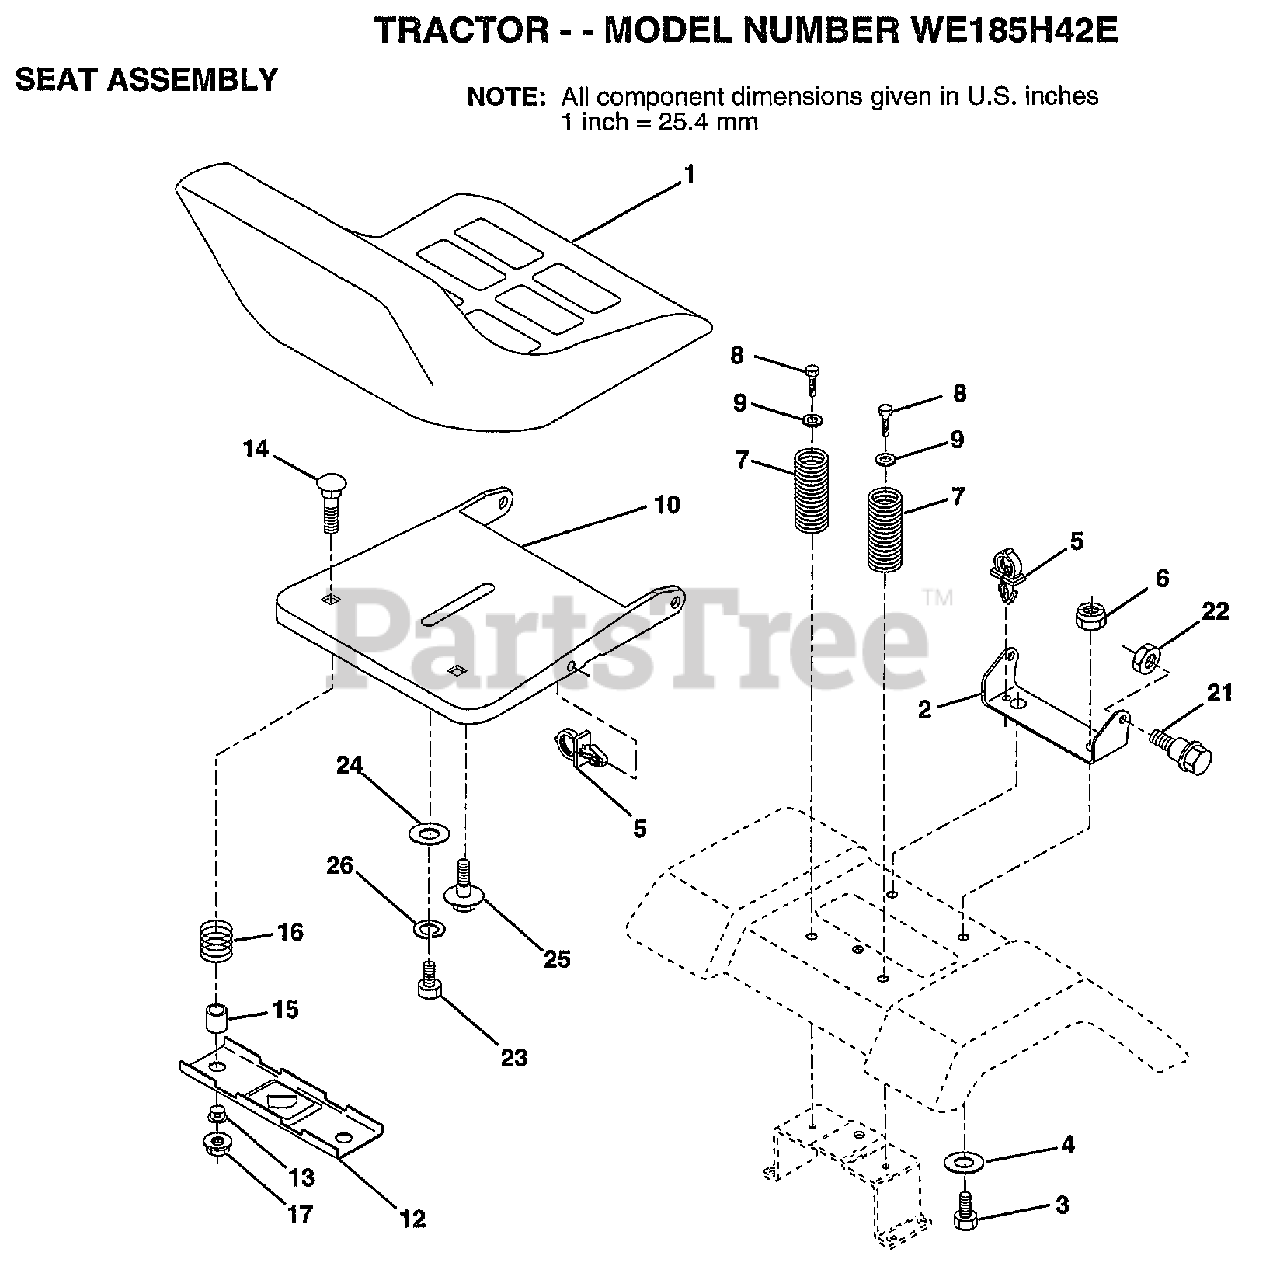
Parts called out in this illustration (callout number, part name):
2	BRACKET PVT SEAT
3	BOLT
4	WASHER PM
5	CLIP.PUSH-IN.HING
6	NUT
7	SPRING COMPRESSIO
8	SCREW GTV
9	WASHER
10	PAN-SEAT
12	BRKT SWITCH
13	BUSHING
14	BOLT-RD HD SQ NK
15	SPLIT SPACER
16	SPRING
21	"BOLT,SHOULDER"
22	NUT
23	BOLT
24	WASHER
25	"BOLT,SHOULDER"
26	LOCKWASHER
